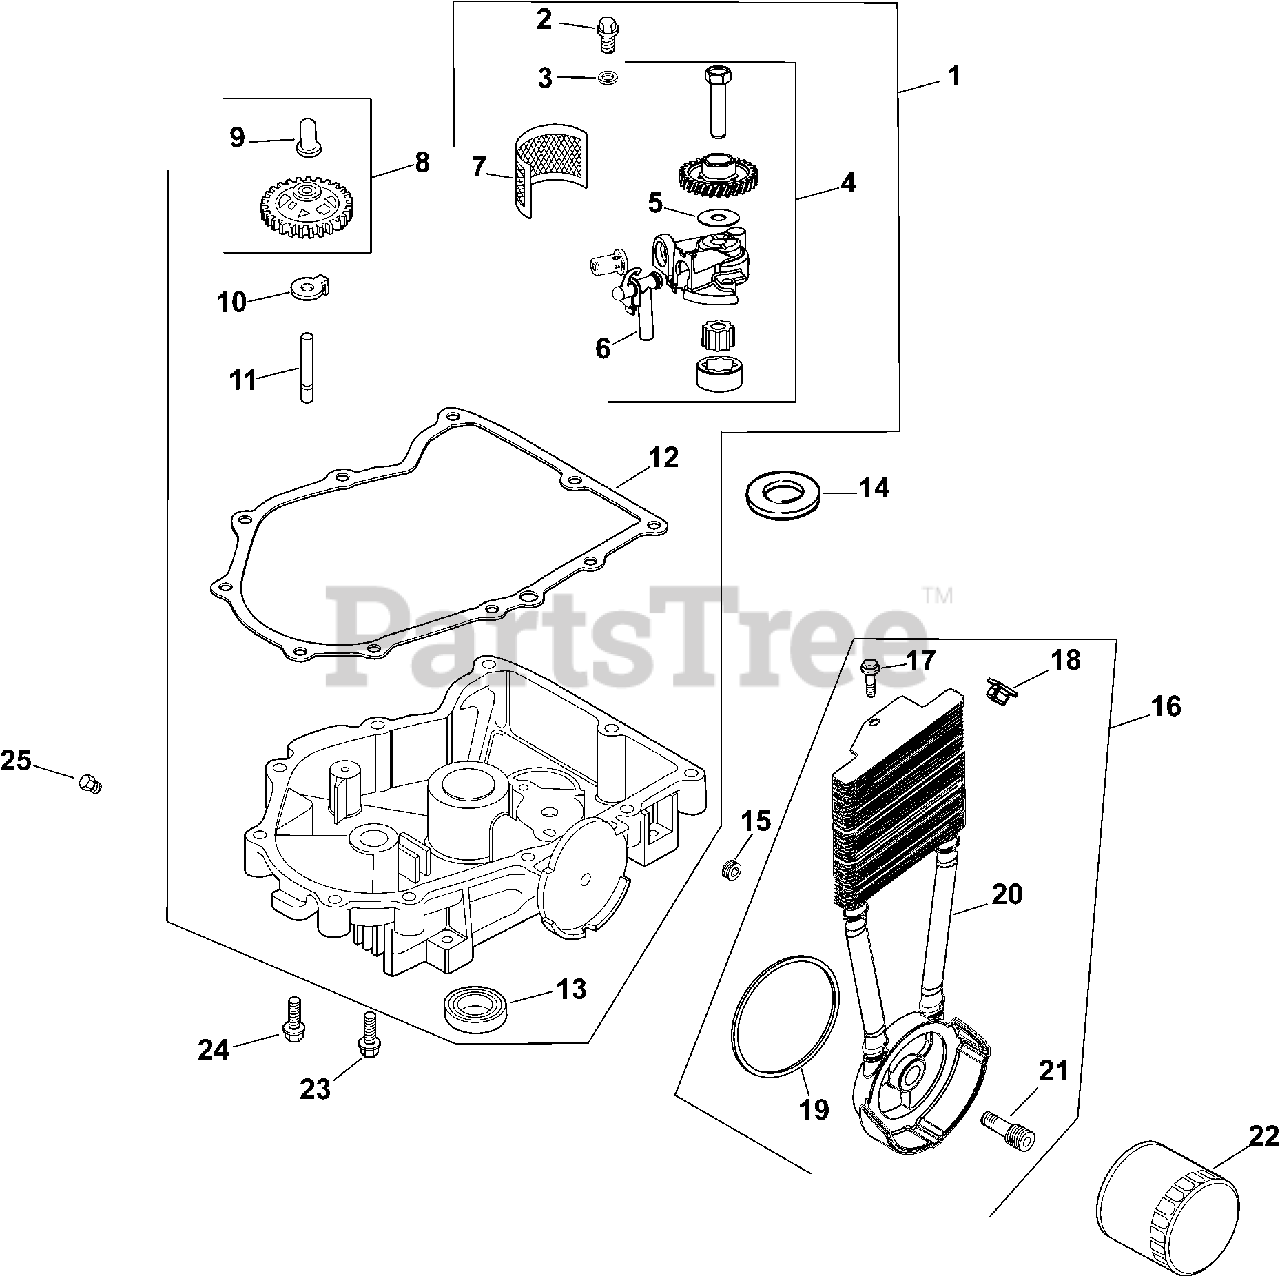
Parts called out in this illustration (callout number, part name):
1	KIT, OIL PAN W/GASKET USE 24 199 32-S
2	SCREW,FLG THD FRM M6X1.0X25-(#25086395S)
3	WASHER, FLAT 6 MM
4	OIL PUMP ASSY KIT-USE 24 393 53-S
5	O-RING, OIL PICK-UP
6	KIT, OIL PICK-UP TUBE
7	SCREEN, OIL
8	KIT, GOVERNOR GEAR W/PIN
9	PIN, GOVERNOR REGULATING
10	TAB, LOCKING
11	SHAFT, GOVERNOR GEAR
12	KIT,OIL PAN GASKET USE 24 041 66-S
13	SEAL, OIL (KM)-USE 25 032 06-S
14	SHIM, THRUST (GREEN .875MM) - DISCONTINUED
15	PLUG, PIPE CTSK 3/8"
16	KIT, OIL COOLER
17	SCREW, TAP M6X1.7X18
18	NUT, PLASTIC (KM)-USE 25 100 37-S
19	O-RING, OIL COOLER
20	COOLER, OIL - PHENOLIC-USE 24 594 36-S
21	NIPPLE, OIL FILTER
22	OIL FILTER
23	SCREW, HEX FLANGE -USE 24 086 17-S
24	SCREW, FLG M8X1.25X45
25	PLUG, HD PIPE 3/8"
M-545020-S	SCREW, FLG THD FRM M5X.8X20-(#25086399S)
